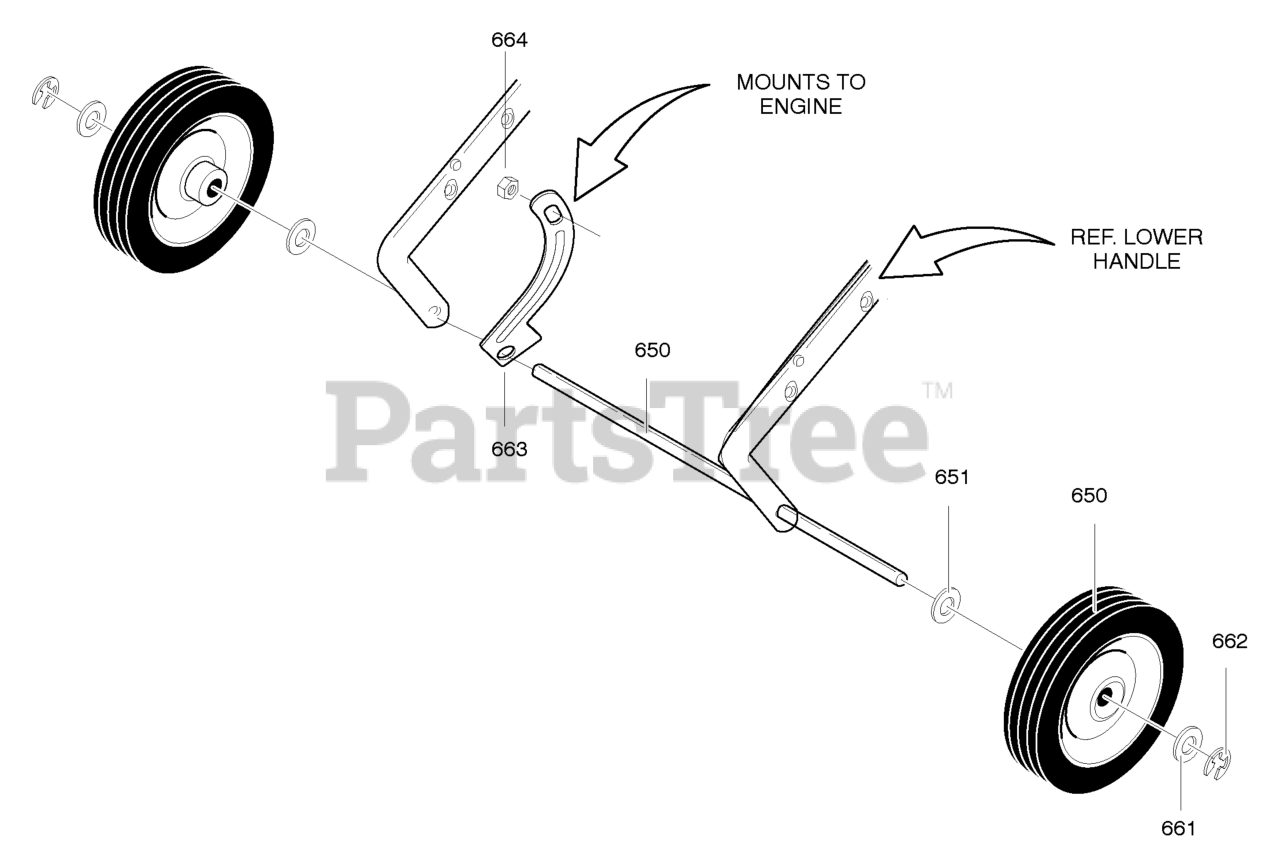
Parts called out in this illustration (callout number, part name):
650	AXLE SHAFT
651	WASHER, FLAT .391X1.00X1.25
660	TIRE & RIM
661	WASHER, FLAT .391X1.00X.125
662	RING, RET E
663	BRACKET, AXLE
664	NUT
